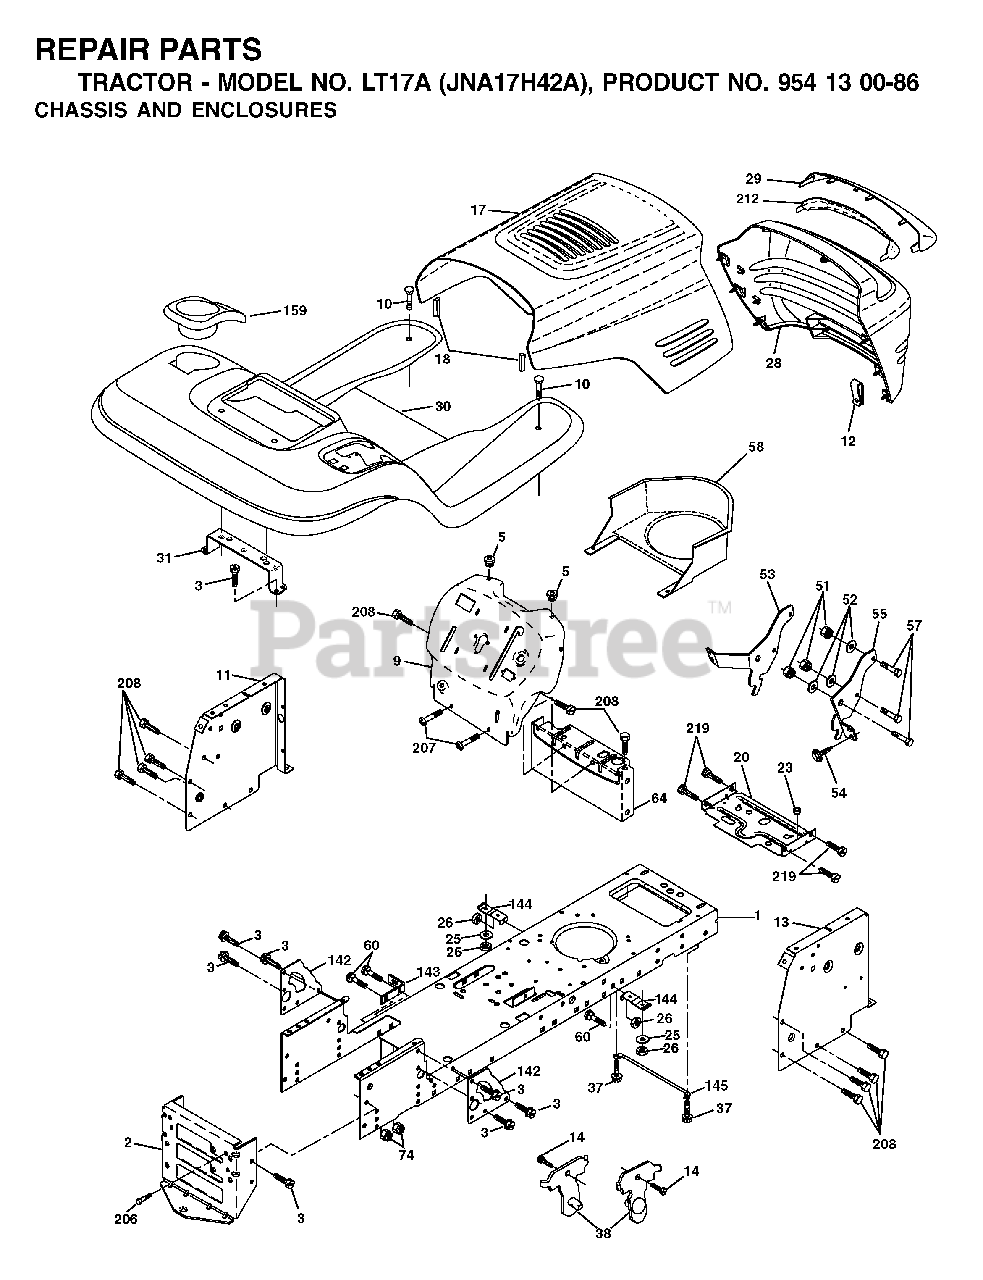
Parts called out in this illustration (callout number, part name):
1	CHASSIS STAMPING
2	DRAWBAR, 12GA
3	SCREW 3/8-16X3/4
5	BUMPER.RUBBER.HOOD
10	BOLT D
11	PANEL.DASH.LH.LTX
13	PANEL ASM, DASH RH
18	BUMPER HOOD T
20	PLATE MTG.BATTERY/FUEL TANK
23	GROMMET T
25	WASHER
26	NUT
28	GRILL/LENS ASM.
38	BRACKET.ASM.PIVOT.MOWER.REAR
51	LOCKNUT
53	BRACKET.GRILLE.LH
57	BOLT
58	AIR DUCT P/L/LT
64	DASH LOWER
74	LOCKNUT
142	PLATE REINFORCEMENT
143	BRACKET, SWAY BAR
144	BRKT, FOOT REST
145	ROD PIVOT CHASSIS/HOOD
206	SHOULDER BOLT 5/16-18TT
207	SCREW, 5/16-18 X 1/2
208	SCREW 3/8-16X1/2
219	SCREW
